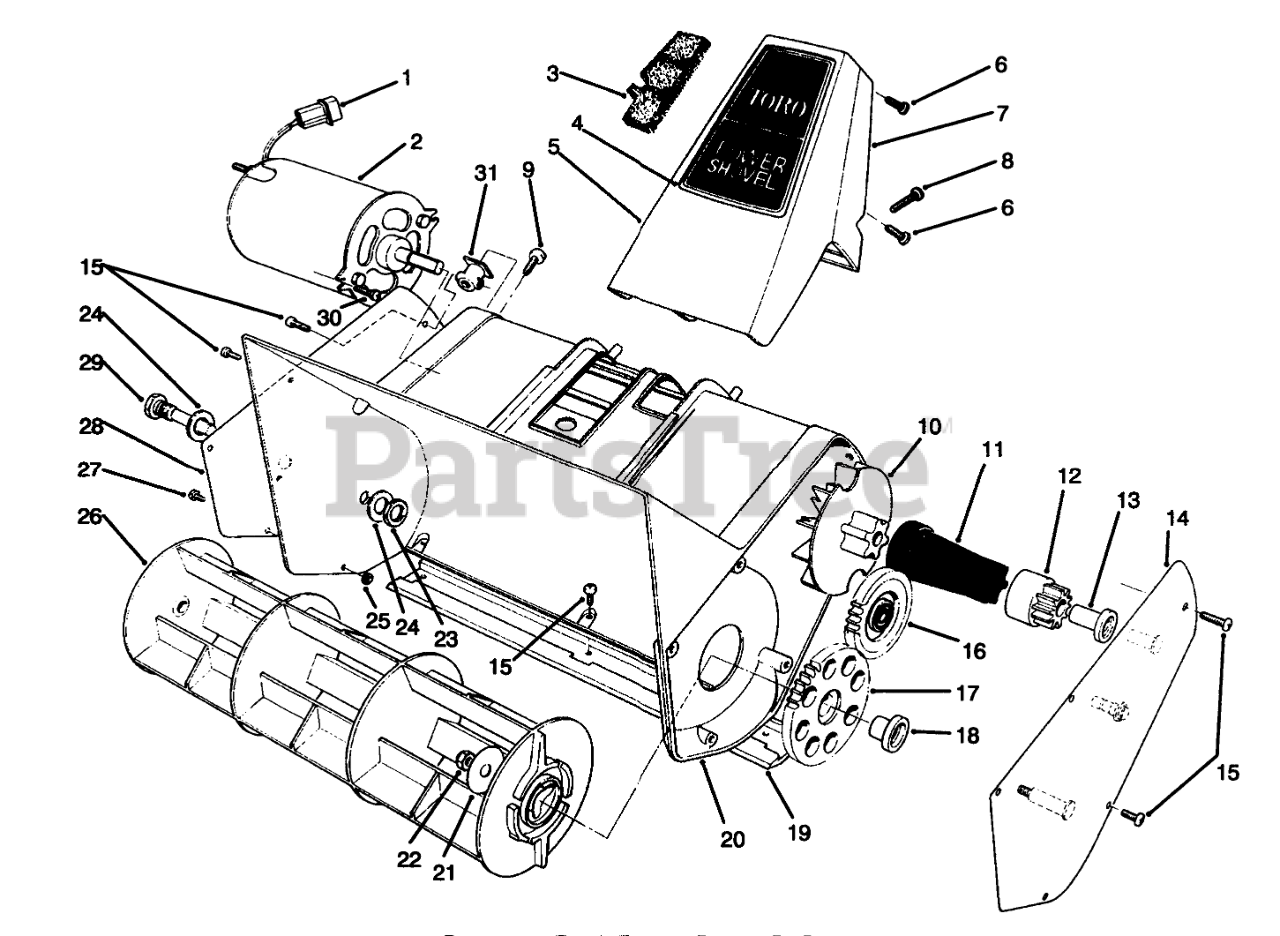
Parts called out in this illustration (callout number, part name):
1	HSG PIN CONNECTOR
2	Motor-(Incl. Ref. #1)
3	FOAM FILTER
4	HANDLE SUPT DECAL
5	FRONT HANDLE SUPPORT
6	Screw
7	HANDLE SUPPORT BACK
8	SCREW-PPH
9	#10-10X3/4 PLASCREW
10	FAN, POWER SHOVEL
11	DRIVE COUPLING
12	Drive Gear (Incl. Ref. #13)
13	BUSHING, DRIVE GEAR
14	Gear Carrier
15	SCREW-PPH
16	IDLER GEAR ASM
17	Rotor Gear Assembly (Incl. ref. #18)
18	BUSHING, ROTOR GEAR
19	1200 SCRAPER, 12"
20	Housing
21	ROTOR WASHER
22	NUT-LOCK, NI
23	NUT-LOCK, CONE
24	WASHER-FLAT
25	NUT-LOCK
26	ROTOR
27	SCREW-PPH
28	RT. SIDE COVER (RAW)
29	ROTOR PIN
30	SCREW-PPH
31	MOUNTING BLOCK
